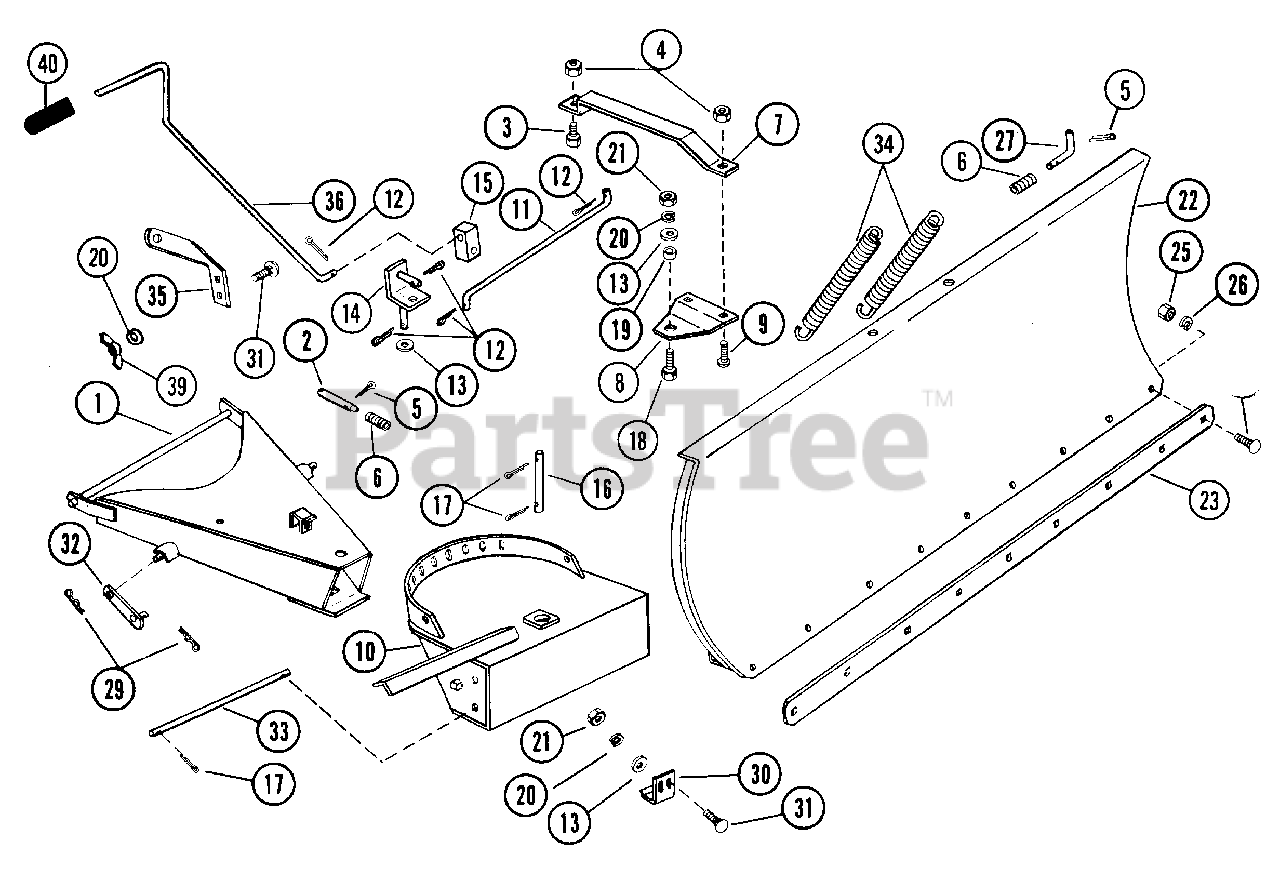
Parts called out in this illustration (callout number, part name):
1	54 INCH FRAME
2	LATCH PIN
3	BOLT, HEX 5/16-18X1.25
4	NUT, LOCK 5/16-18
5	PIN, COTTER .125X1.00
6	COMPRESSION SPRING
7	STRAP
8	PIVOT PLATE
9	BOLT, CARRIAGE 5/16-18X.75
10	SUPPORT
11	ROD
12	PIN, COTTER .125X.75
13	WASHER, FLAT .438X1.000X.083
15	UNIVERSAL BLOCK JOINT
16	PIN
17	PIN, COTTER .187X1.25
18	BOLT, HEX 3/8-16X1.00
19	SPACER
20	WASHER, LOCK 3/8 REG.
21	NUT, HEX 3/8-16
22	54 INCH BLADE
23	PLATE, WEAR
24	BOLT, CARRIAGE 5/16-18X1.00
25	NUT, HEX 5/16-18
26	WASHER, LOCK 3/8 SP HEAVY
27	JACK PIN
29	PIN, HAIR
30	SKID SHOE
31	HAIRPIN, INTERNAL
32	ARM
33	ROD
34	EXTENSION SPRING
35	SUPPORT
36	ROD
39	NUT, WING 3/8-16 PL
40	GRIP, 3/8 I.D.X2-7/8 BLACK
NS	CAUTION DECAL, BLADE
NS	DECAL, AMERICA
